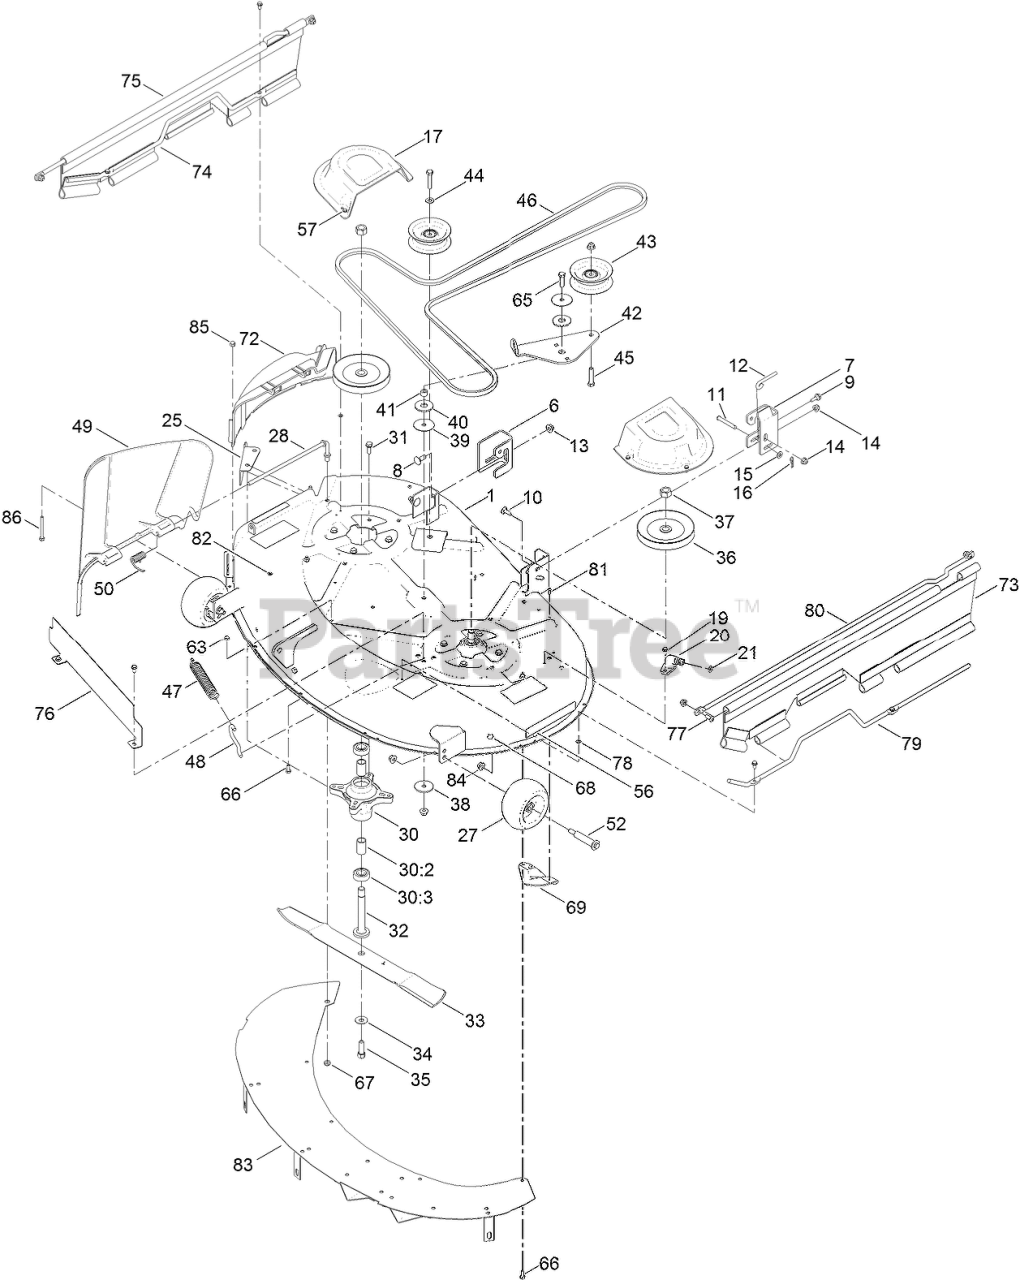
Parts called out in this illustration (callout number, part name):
1	42 INCH DECK AND DECAL ASM
6	BRACKET-HANGER, RH
7	BRACKET-HANGER, LH
8	BOLT-CARR
9	SCREW-SHOULDER, HHF
10	SCREW-CARR
11	PIN-CLEVIS
12	ROD-LEVEL, DECK
13	NUT-HF, NI
14	NUT-HF, NI
15	WASHER-PLAIN
16	PIN-COTTER
17	COVER-BELT
19	SCREW-HWH
20	FITTING-WASHOUT
21	O-RING
25	BAFFLE-CUTOFF
27	ROLLER-SCALP, ANTI
28	ROD-PIVOT
30	SPINDLE ASM
30:2	SPACER
30:3	BEARING-BALL
31	SCREW-TAPTITE
32	SHAFT-SPINDLE
34	WASHER-BELLEVILLE
35	SCREW-HH
36	Pulley
37	NUT-HEX
38	WASHER-REBOUND
39	WASHER
40	WASHER-FRICTION, COMPOSITE
41	SPACER
42	ARM-IDLER
43	PULLEY-IDLER, FLAT
44	WASHER-FLAT
45	SCREW-HH
46	V-BELT
47	SPRING-EXTENSION
48	HOOK-RETURN, SPRING
49	DEFLECTOR
50	SPRING-TORSION
52	BOLT-SHOULDER
56	DECAL-RECYCLER
57	SCREW-TAPTITE
63	NUT-LOCK, NI
65	SCREW-HH
66	SCREW-HH
67	NUT-LOCK, NI
68	SCREW-HH
69	PLATE-KICKER
72	COVER-DISCHARGE
73	ROD-SUPPORT, UPPER
74	ROD-SUPPORT, LOWER (RH)
75	RH GUARD SIDE
76	SHIELD-FRONT, DECK
77	SCREW-HSBH
78	NUT-RETAINING
79	ROD-SUPPORT, LOWER (LH)
80	GUARD-SIDE, LH
81	SCREW-PPH
82	NUT-RETAINING
83	BAFFLE UPPER ASM
84	NUT-HF
85	NUT-CAP
86	SCREW-HH
